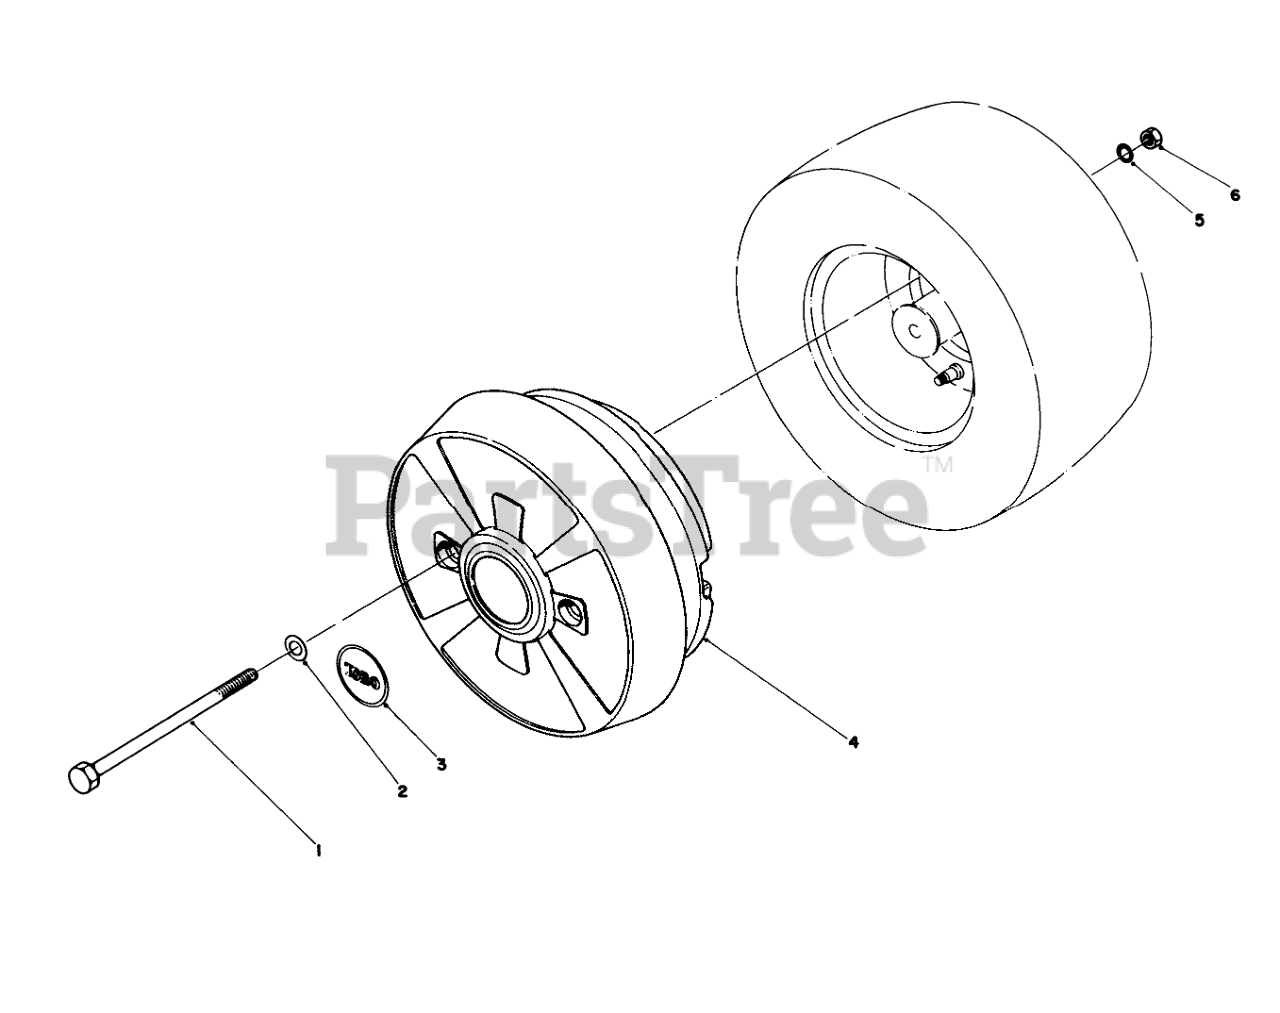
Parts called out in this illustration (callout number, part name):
1	SCREW-HH
2	WASHER-FLAT
3	Decal
4	WHEEL WEIGHT
5	WASHER-LOCK
6	NUT-HEX
